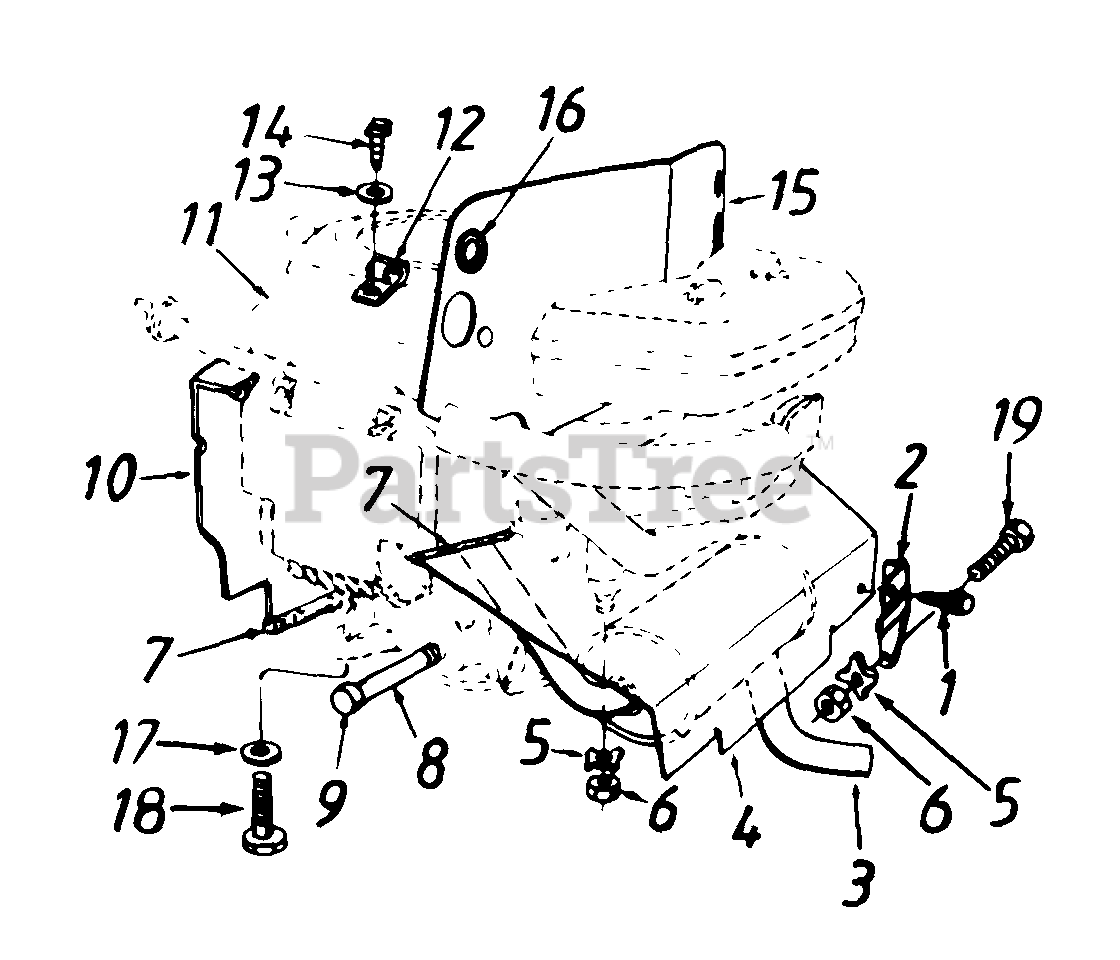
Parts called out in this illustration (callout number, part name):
1	Hex AB-Tap Scr. 1/4 x .62"
3	Muffler
4	Front Heat Shield
5	Spec. L-Wash. 5/16 x .88"
6	Hex Nut 5/16-18 Thd.
7	Trim Strip 12" Lg.
8	Pipe Nipple
9	Oil Drain Cap
10	Rear Baffle
11	Engine
12	Clamp
13	Fl-Wash. .188" I.D. x .438"
14	Truss Mach, AB-Tap Scr. #10 x .5" Lg.
15	Heat Shield
16	Rubber Grommet
17	Fl-Wash. .406" I.D. x 1-1/4" O.D.
18	Hex L-Wash TT-Tap Scr. 3/8-16 x 1.5" Lg.
19	Hex Bolt 5/16-18 x 5/8" Lg.
